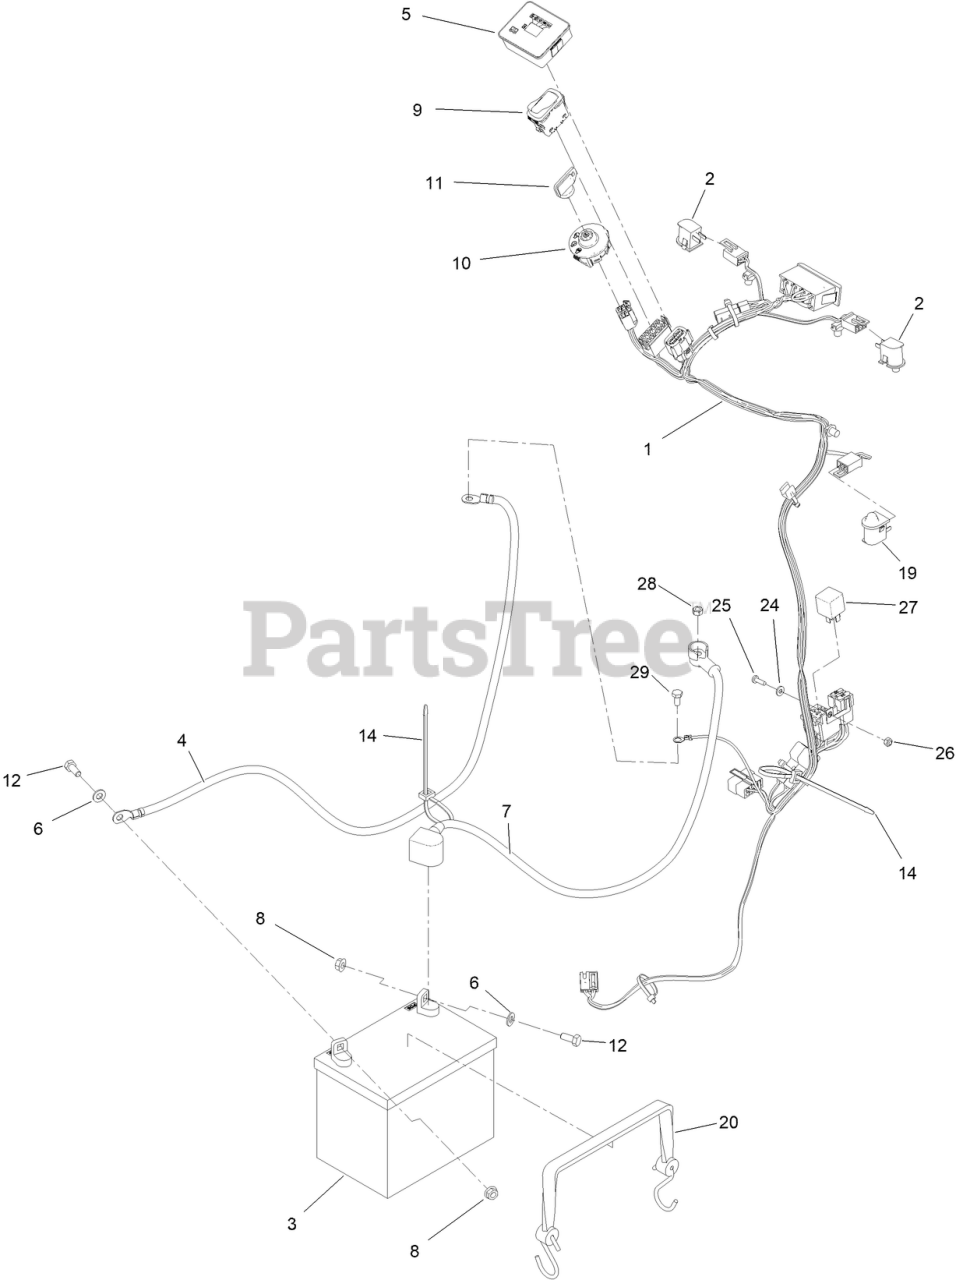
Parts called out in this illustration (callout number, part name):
1	HARNESS-WIRE, GRANDSTAND
2	SWITCH-BAIL
3	BATTERY-DRY
4	BATTERY-CABLE, BK ASM
5	MODULE-METER, HOUR
6	WASHER-PLAIN
7	BATTERY-CABLE, RD ASM
8	NUT-HHF, SMOOTH
9	SWITCH-ROCKER, (ON)-ON-OFF
10	SWITCH-IGNITION
11	KEY-IGNITION
12	SCREW-HH
14	TIE-CABLE
19	SWITCH-PLUNGER
20	STRAP-RUBBER
24	WASHER-FLAT
25	SCREW-PPH
26	NUT-LOCK, NI
28	NUT-HEX
29	SCREW-HH
